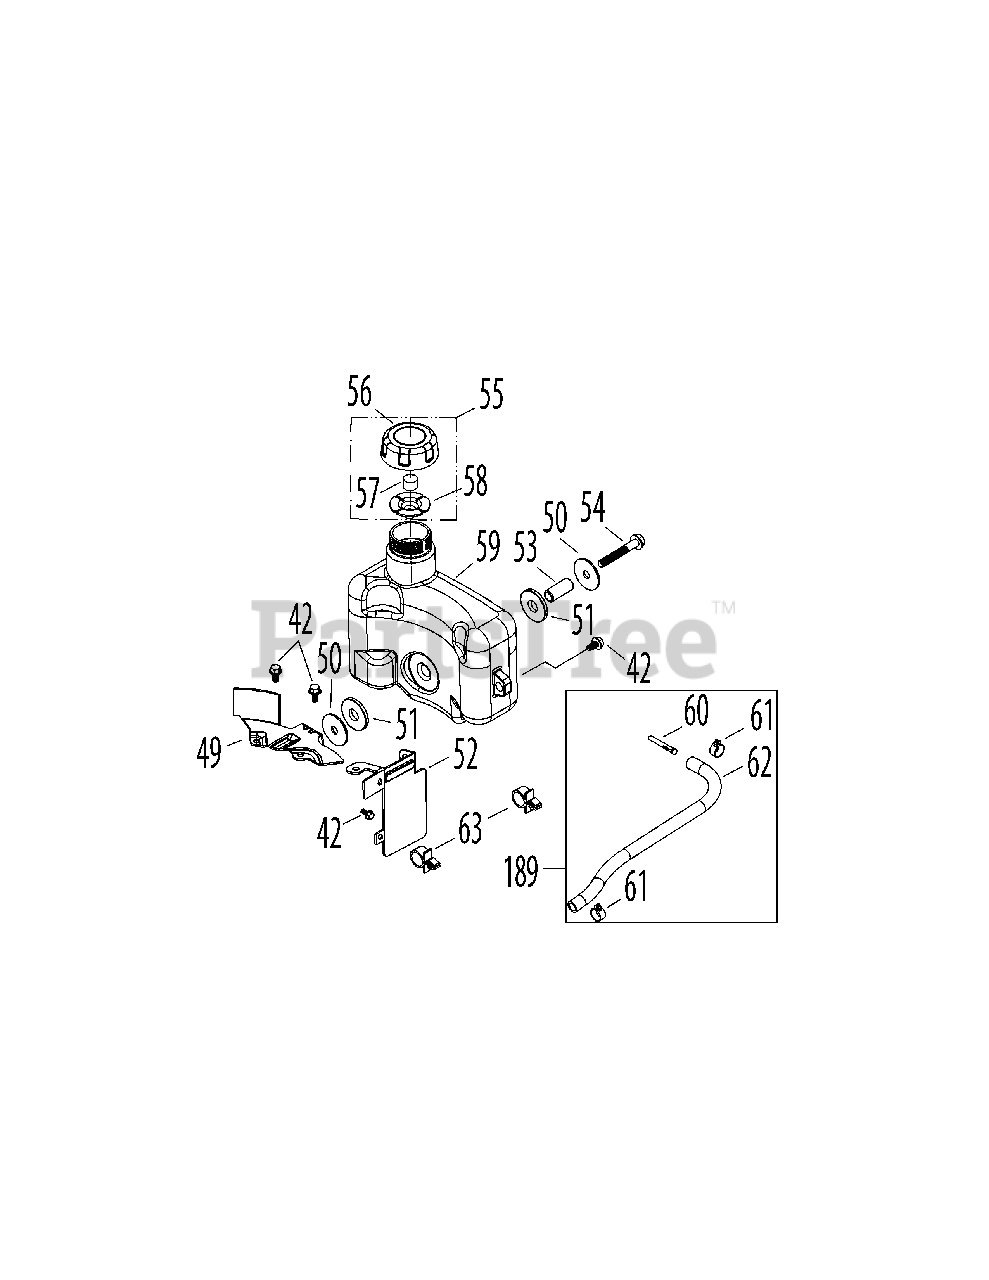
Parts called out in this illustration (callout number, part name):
42	Bolt M6×14
49	Fuel Tank Bottom Bracket
50	Fuel Tank Washer
51	Rubber Bushing
52	Tank/Label Bracket
53	Fuel Tank Bushing
54	Tank Bolt M8×50
55	Fuel Cap Assembly
56	Fuel Cap
57	Foam Insert
58	Vent Gasket
59	Fuel Tank Assembly
60	Fuel Filter
61	Fuel Hose Clamp
62	Fuel Hose
63	Plastic Support Clamp
189	Fuel Line Kit
